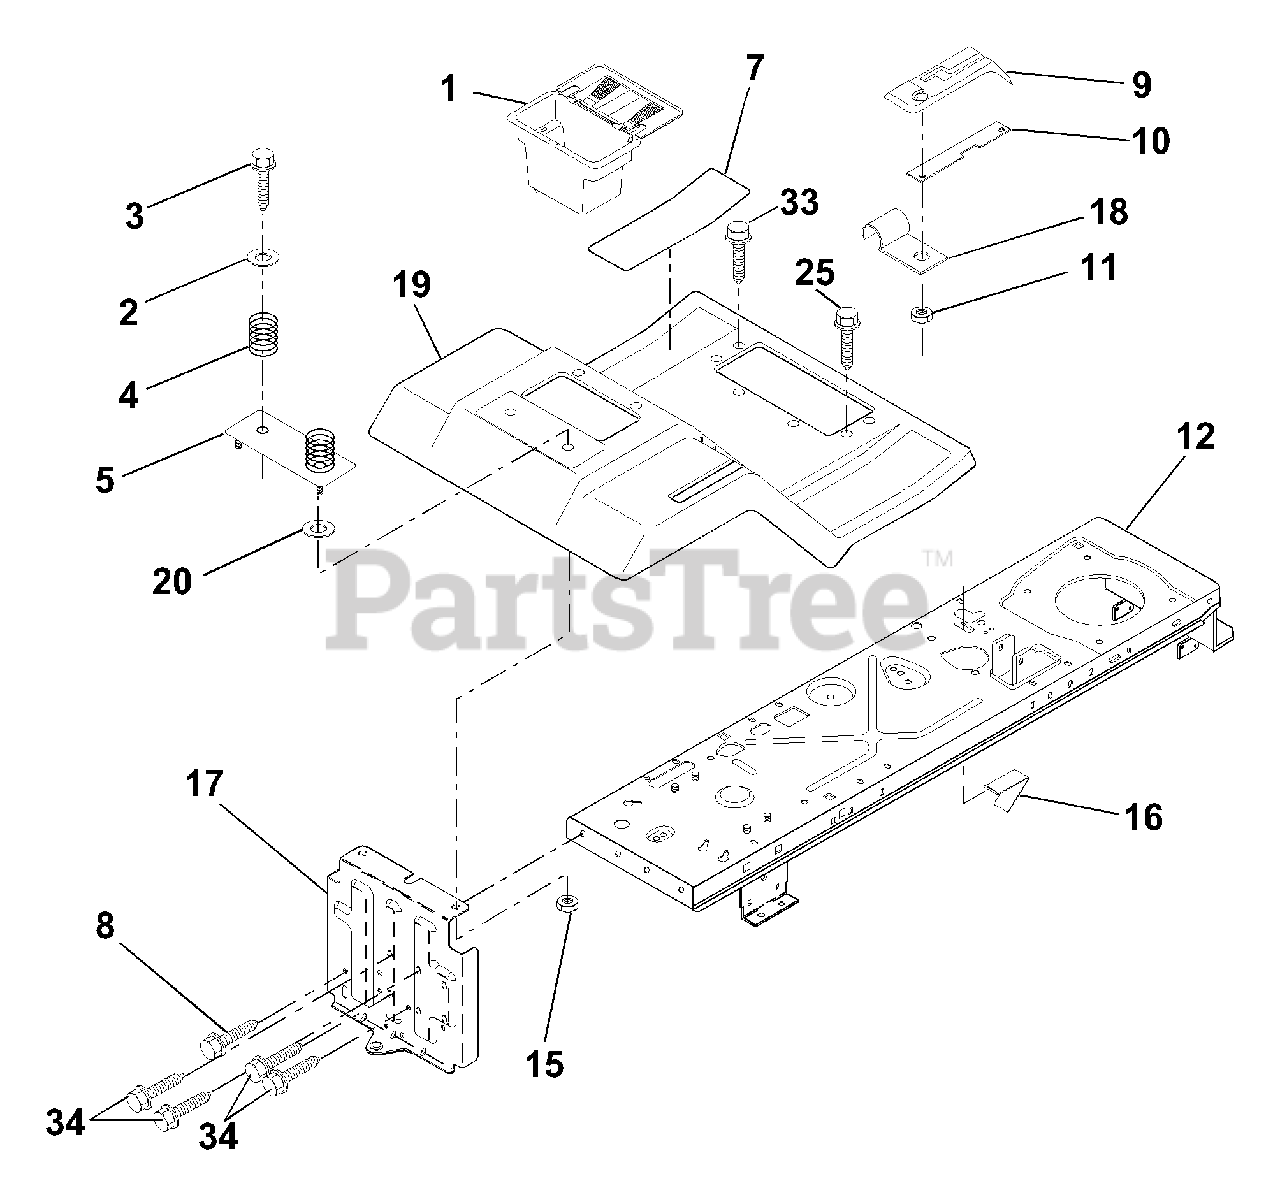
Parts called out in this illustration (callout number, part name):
1	Case, Battery
2	Washer 13/32 x 1-1/4 x 12 Ga.
3	Screw, Hex Wsh. Thrdrol. 3/8-16 x 3/4
4	Spring, Compression, Seat
5	Plate, Asm. Battery
7	Pad, Footrest
8	Screw, Hex Wsh Thdrol. 5/16-18 x 3/4
9	Console, Shift Control
10	Bar, Shift Lock
11	Nut, Self-Thrd., Wsh. Head 3/16
12	Assembly, Frame
15	Nut, Keps Hex 1/4-20 UNC
16	Switch Actuato
18	Clip, Insulated
19	Fender/Footrest
20	Washer 9/32 x 7/8 x 13 Ga.
25	Screw Tapping 5/16-18
33	Screw Hex Wsh Thdroll 5/16-18 x 1
34	Bolt Shoulder 5/16-18 TT
